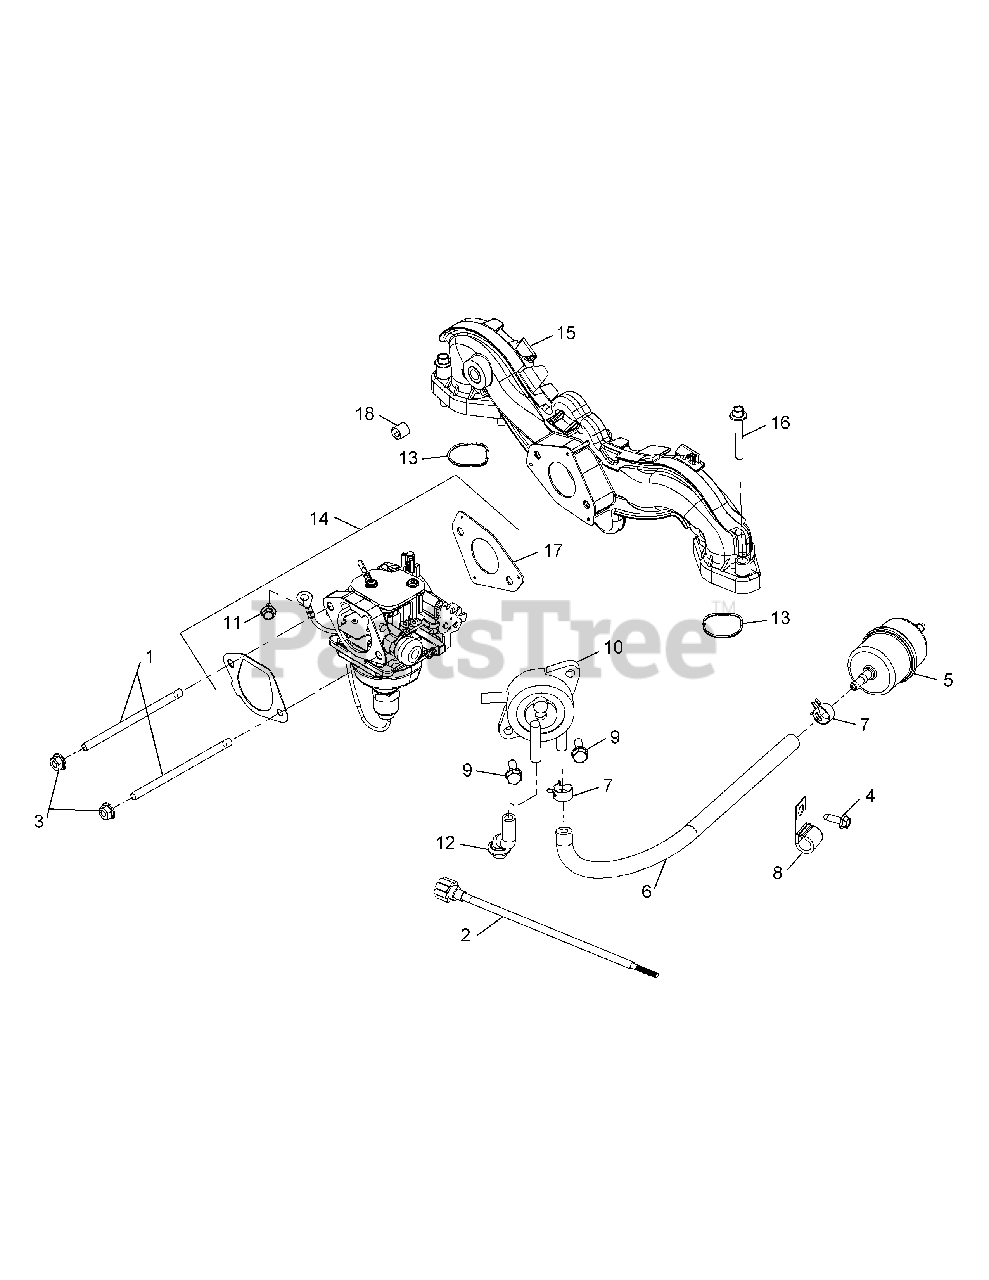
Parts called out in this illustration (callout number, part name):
2	CABLE-CARBURETOR ADJUSTER
3	Flange Nut, M6 x 1.0
4	Thread Forming Screw
5	Fuel Filter
6	Fuel Line, 24"
7	Spring Hose Clamp
9	Tap Screw, M6 x 1.7 x 18
11	Thread Forming Screw
12	Pulse Pump Hose
13	Intake Port O-Ring
14	Carburator Assembly
14	Carburator Kit
15	Intake Manifold Kit
16	Flange Screw, M6 x 1.0 x 40
17	CARBURETOR GASKET
18	Pipe Plug, 1/8
